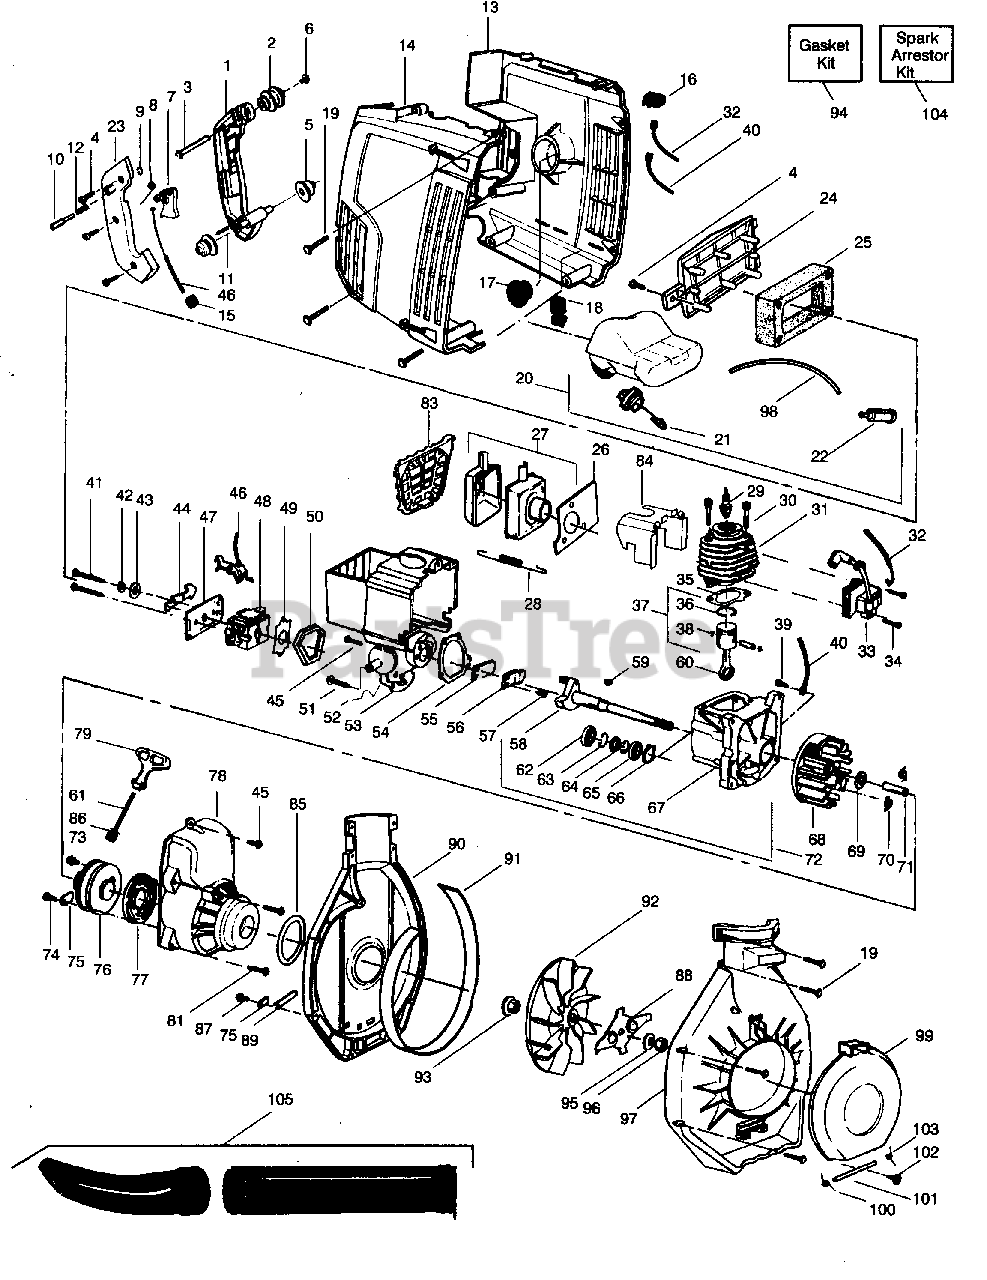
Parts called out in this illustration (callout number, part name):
1	Handle
2	Front Isolator
4	Screw-Handle
5	Rear Isolator
9	"C" Clip
10	Throttle Lock Button
12	Spring-Throttle Lock
13	Shroud-Left
14	Shroud-Right
15	Grommet-Carb.
16	Switch Kit
17	Isolator-Engine Mount
18	Isolator-Tank
19	Screw-Shroud/Blower Hsg.
20	Fuel Tank Ass'y.
21	Fuel Cap (Incl. O'Ring)
22	Fuel Pick-up Ass'y.
23	Handle Cover/Throttle Lock Ass'y. (Incl. 9, 10 & 12)
24	Cover-Air Filter
25	Air Filter
26	Muffler Gasket
29	Spark Plug
31	Cylinder
32	Lead Wire
33	Ignition Module
35	Gasket-Cylinder
36	Piston Rings
37	Piston Kit (Incl. 36, 38, & Pin)
38	Retainer
40	Ground Wire
42	Wave Washer
43	Spacer-Choke
44	Choke Shutter
45	Screw-Reed
46	Throttle Cable Assembly
47	Plate-Air Filter
48	Carburetor Ass'y. (WT-141A) (Incl. Limiter Cap)
49	Gasket-Carb
50	Seal-Reed Block
52	Ground Wire-Static
53	Reed Block
54	Gasket-Reed Block
55	Reed Valve
56	Reed Stop
58	Crankshaft
60	Connecting Rod Ass'y.
61	Rope Kit
62	Inner Bearing
63	Retaining Ring-Crankcase
64	Crankshaft Seal
65	Outer Bearing
66	Retaining Ring-Crankshaft
67	Crankcase Ass'y (Incl. 62-65)
68	Flywheel Ass'y. (Incl. 70)
69	Washer
71	Spacer-Flywheel
72	Crankcase/Crankshaft Assy. (Incl. 58, 62-67)
75	Retainer
76	Starter Pulley (Incl. 73)
77	Starter Spring
78	Fan Housing Kit (Incl. 61, 71, 73-76, 79 & 86)
79	Starter Handle
82	Hex Wrench 5/32"
83	Muffler Guard Kit (Incl. 82)
84	Air Baffle
85	"O" Ring
87	Screw
88	Mulch Blade
89	Roll Pin
90	Blower Housing (Upper)
92	Impeller (Incl. 93)
93	Hub-Impeller
94	Gasket Kit
97	Blower Housing (Lower) (Incl. 99-103)
98	Line Kit
99	Door-Inlet
100	Spring-Right
103	Spring-Left
104	Spark Arrestor Kit
105	Ass'y-Tube and Nozzle
